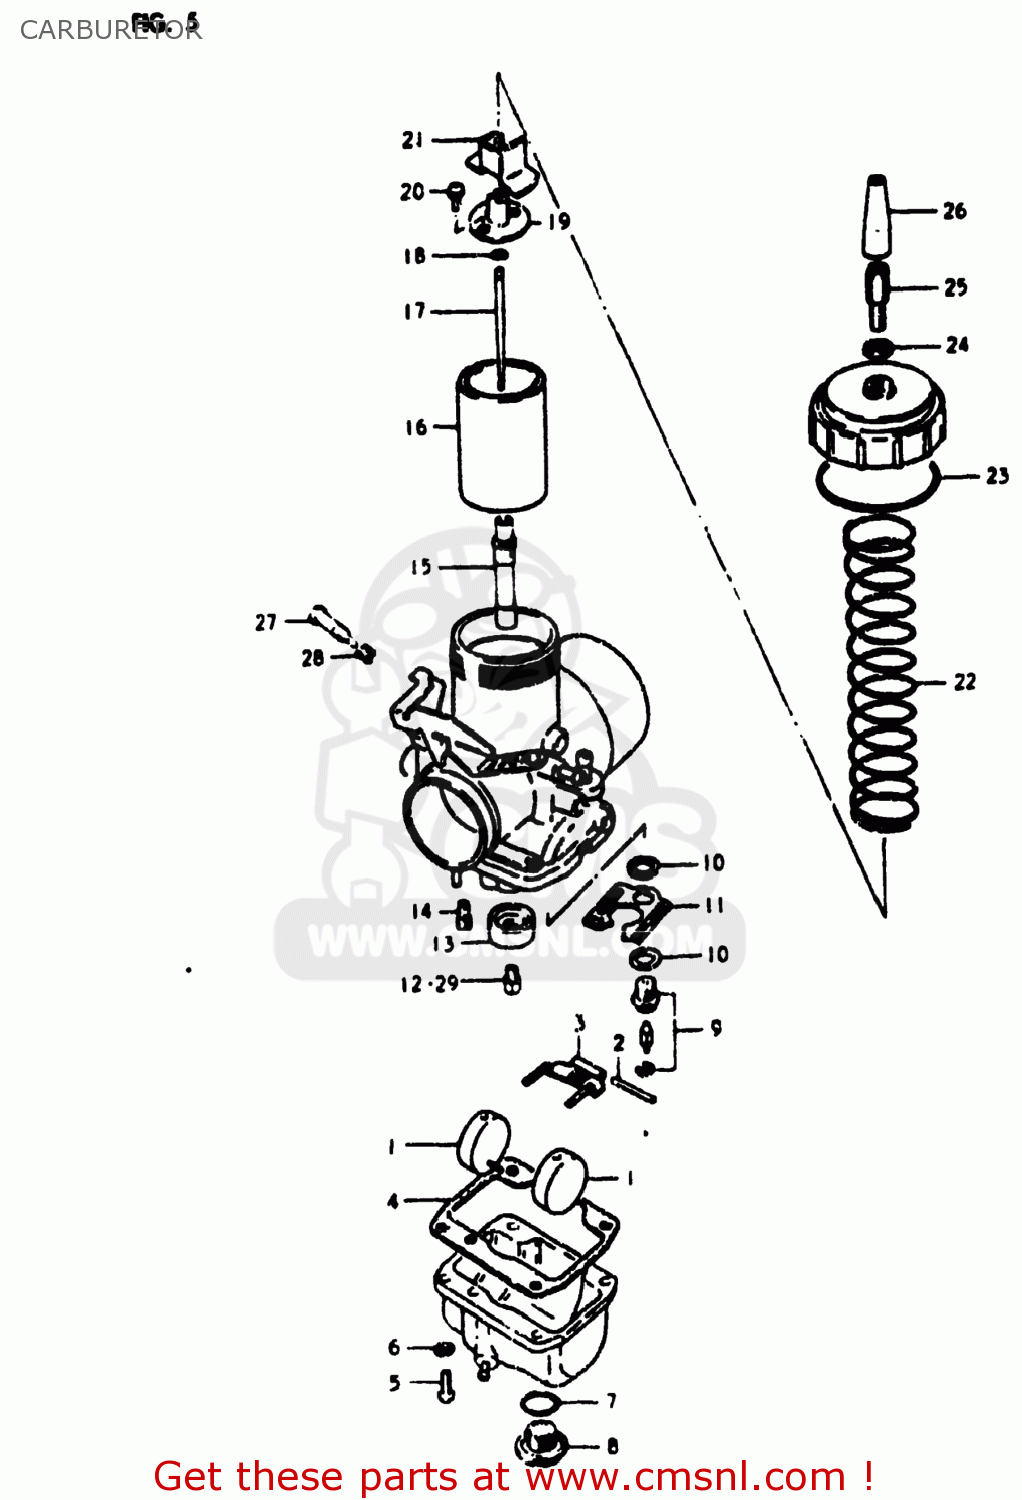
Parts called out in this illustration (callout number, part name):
1	FLOAT
2	PIN,FLOAT
3	ARM,FLOAT
4	GASKET,FLOAT CAHMBER (NAS)
5	SCREW
6	LOCK WASHER
7	O-RING
8	PLUG
9	VALVE ASSEMBLY,NEEDLE
10	GASKET,MAIN JET HOLDER (NAS)
11	PLATE
12	JET
13	RING
14	JET,PILOT(50)
15	JET,NEEDLE
16	VALVE,THROTTLE
17	JET,NEEDLE(6FJ6-3)
18	CLIP
19	CONNECTOR
20	SCREW
21	COVER,HOLDER
22	SPRING,THROTTLE VALVE RETURN
23	GASKET,MIXING CHAMBER (NAS)
24	NUT
25	ADJUSTER,CABLE
26	CAP,CABLE ADJUSTER
27	SCREW,PILOT AIR
28	SPRING
29	JET
